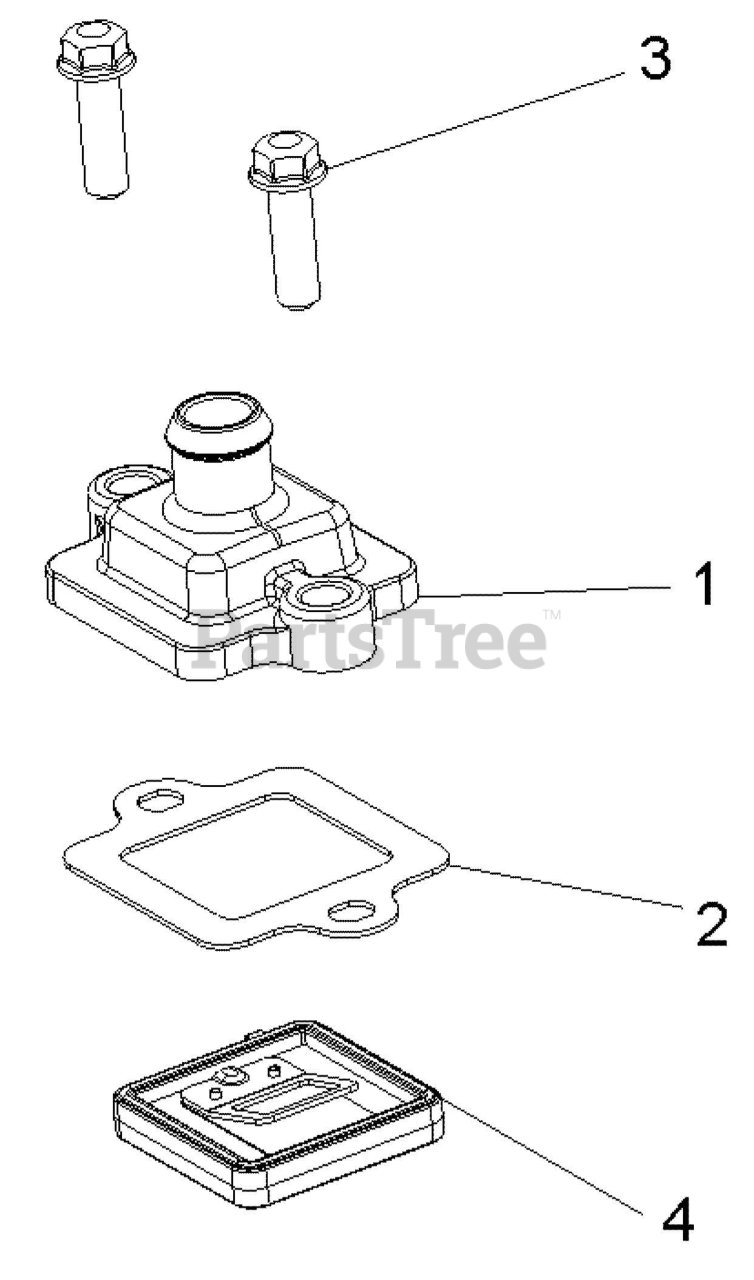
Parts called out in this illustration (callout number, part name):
1	COVER-BREATHER,MACH
2	GASKET-BREATHER,COVER
3	SCR-M6X20,HXFLG,0600214
4	ASM-REED W/GASKET
